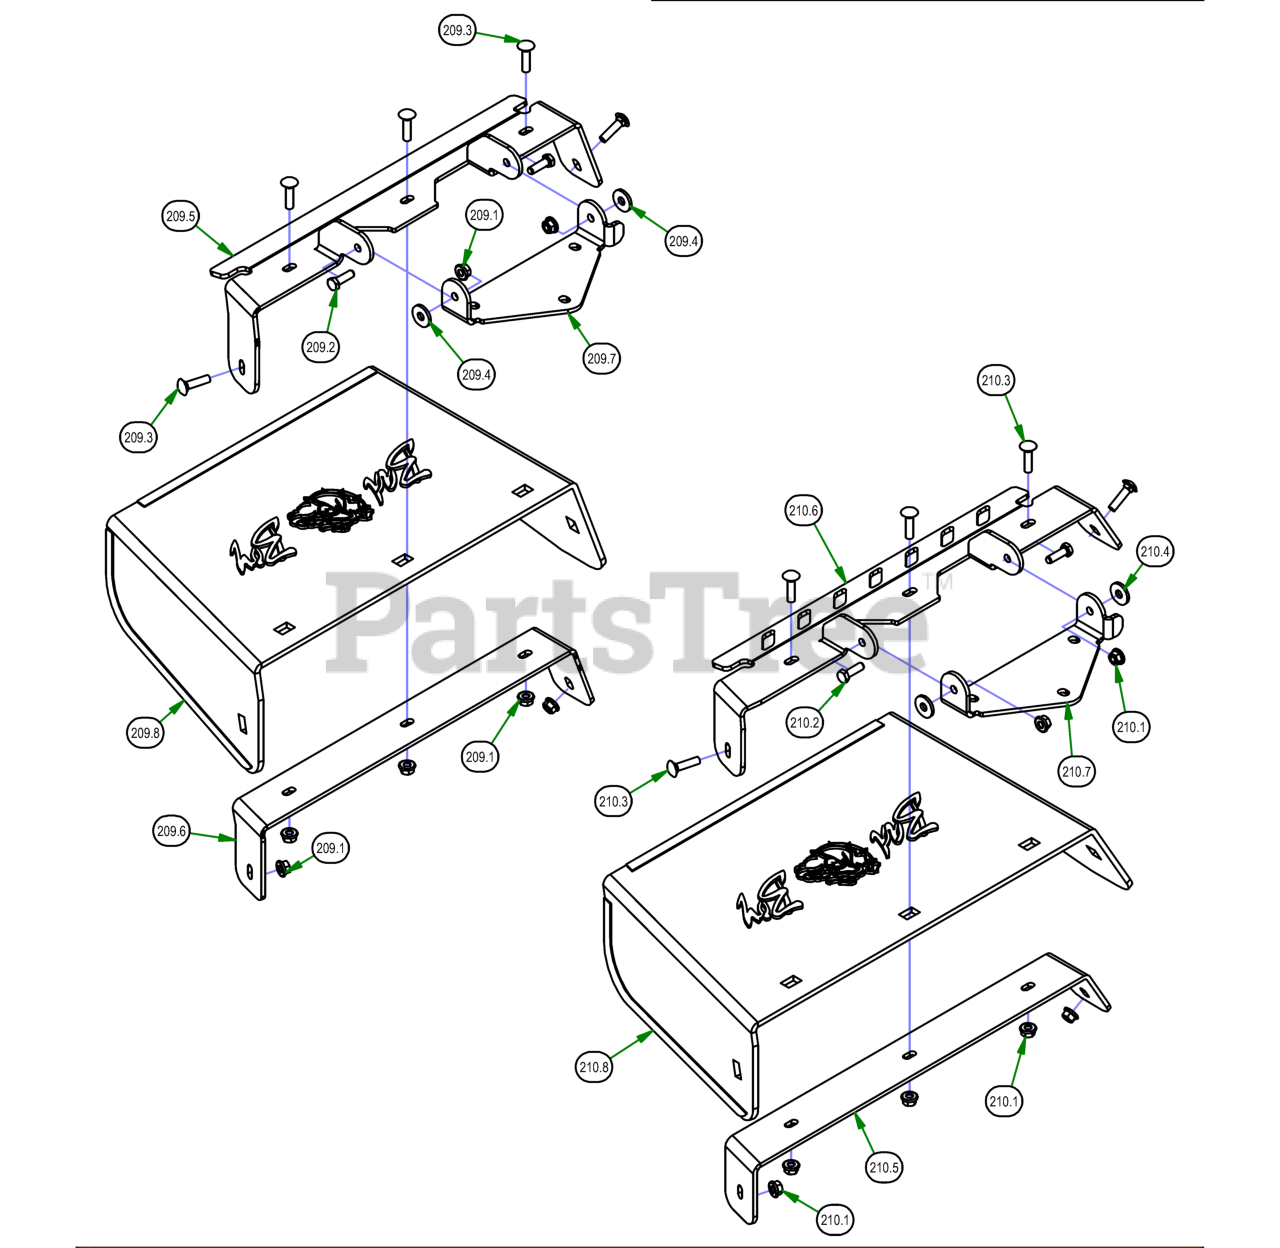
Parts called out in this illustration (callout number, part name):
209	ZT Chute Assembly
209.1	5/16-18 NYLON INSERT FLANGE LOCKNUT ZINC
209.2	5/16-18 X 1 HEX CAP SCREW (GR.5) ZINC
209.3	5/16-18 X 1-1/4 CARRIAGE BOLT ZINC
209.4	.360 ID X .983 OD X .120 THICK FLAT WASHER NYLON
209.5	Discharge Upper Chute Bracket
209.6	Discharge Lower Chute Bracket
209.7	Discharge Chute Hanger (deck mounted)
209.8	Rubber Discharge Chute
210	Discharge Chute Assembly
210.1	5/16-18 NYLON INSERT FLANGE LOCKNUT ZINC
210.2	5/16-18 X 1 HEX CAP SCREW (GR.5) ZINC
210.3	5/16-18 X 1-1/4 CARRIAGE BOLT ZINC
210.4	.360 ID X .983 OD X .120 THICK FLAT WASHER NYLON
210.5	60" Discharge Lower Bracket
210.6	60" Discharge Chute Upper Hanger
210.7	Discharge Chute Hanger (deck mounted)
210.8	Rubber Discharge Chute
